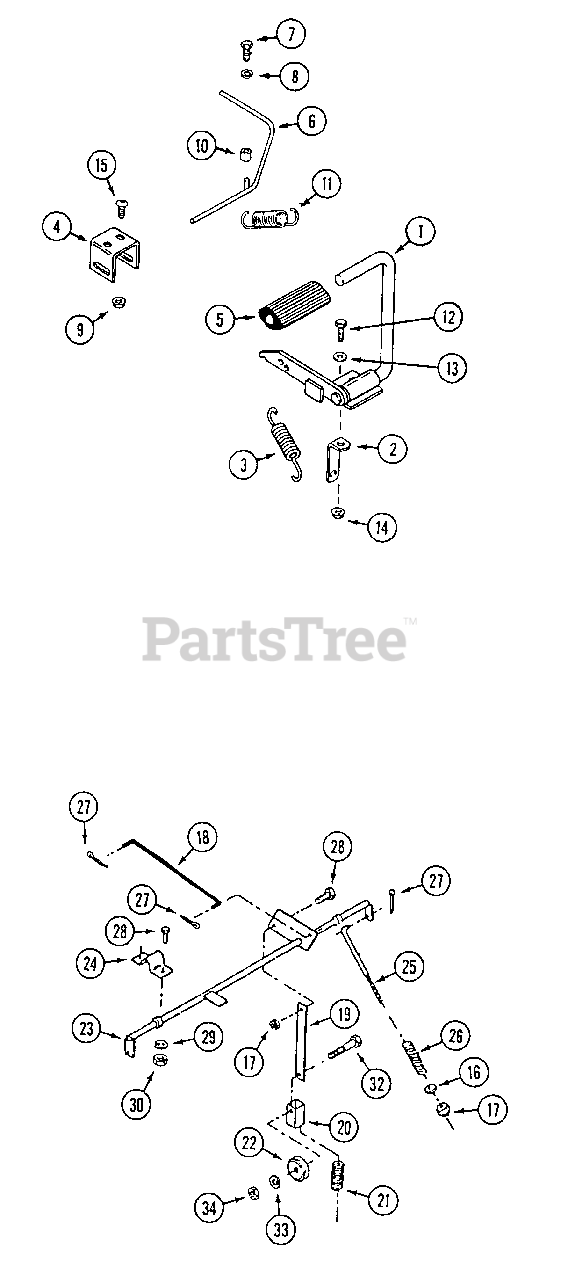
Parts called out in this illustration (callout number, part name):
1	PEDAL - parking brake
2	TAB - spring mount
3	SPRING - brake return
4	BRACKET - brack lock
5	PAD - brake pedal
6	LEVER - brake lock
7	SCREW - 5/16" - 18 x 5/8" allen head
8	LOCKWASHER - 5/16"
9	NUT - 1/4" - 20 flange lock
11	SPRING - return, lock lever
12	BOLT - 5/16" - 18 x 1"
13	WASHER - 5/16"
14	NUT - 5/16" - 18 flange lock
15	SCREW - 1/4" - 20 x 1/2" allen head
16	WASHER - 1/4"
17	NUT - 1/4" - 20 lock
18	ROD - brake pedal
19	LINK - idler pulley
20	TUBE - drive idler
21	SPRING - idler
22	PULLEY - idler
23	ROD - cross, brake and clutch
24	BEARING - cross rod
26	SPRING - caliper
27	PIN - cotter 3/32" x 1"
28	BOLT - 1/4" - 20 x 3/4"
29	LOCKWASHER - 1/4"
30	NUT - 1/4" - 20
